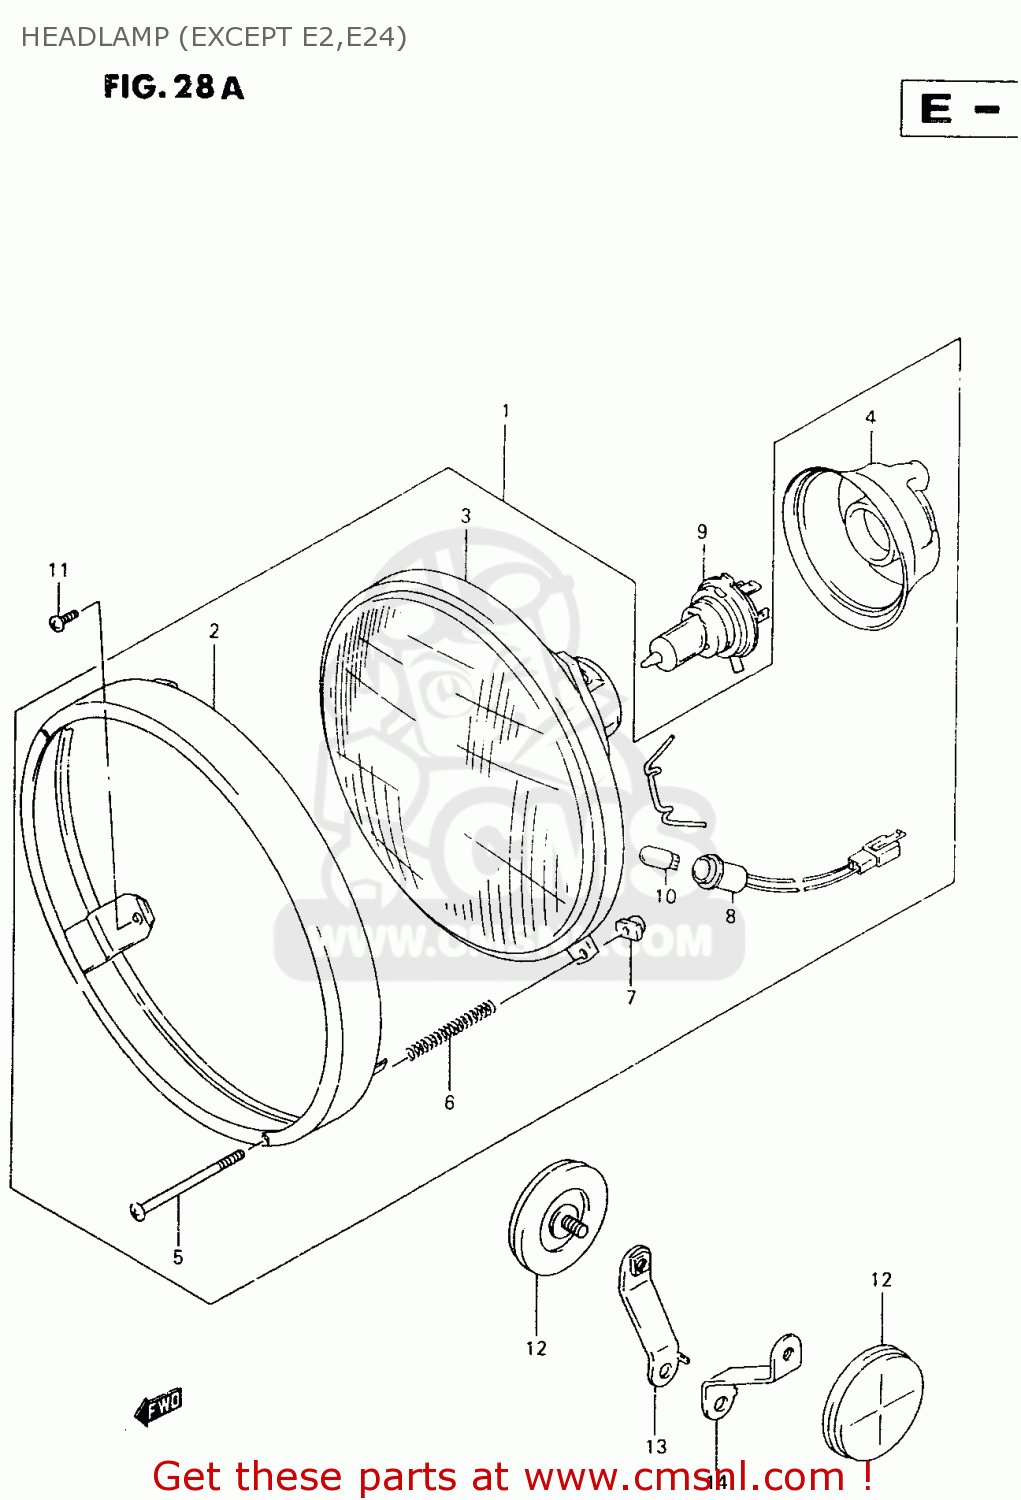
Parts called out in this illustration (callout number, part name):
1	HEADLAMP ASSY
2	RIM ASSY
3	LAMP UNIT
4	COVER,SOCKET
5	SCREW
6	SPRING,ADJUSTING
7	NUT
8	SOCKET,PARKING LAMP
9	BULB(12V60/55W,H4)
10	BULB(12V4W)
11	SCREW(5X12)
12	REFLECTOR,REFLEX FR
13	BRACKET,FR SIDE RR,R
14	BRACKET,FR SIDE RR,L
